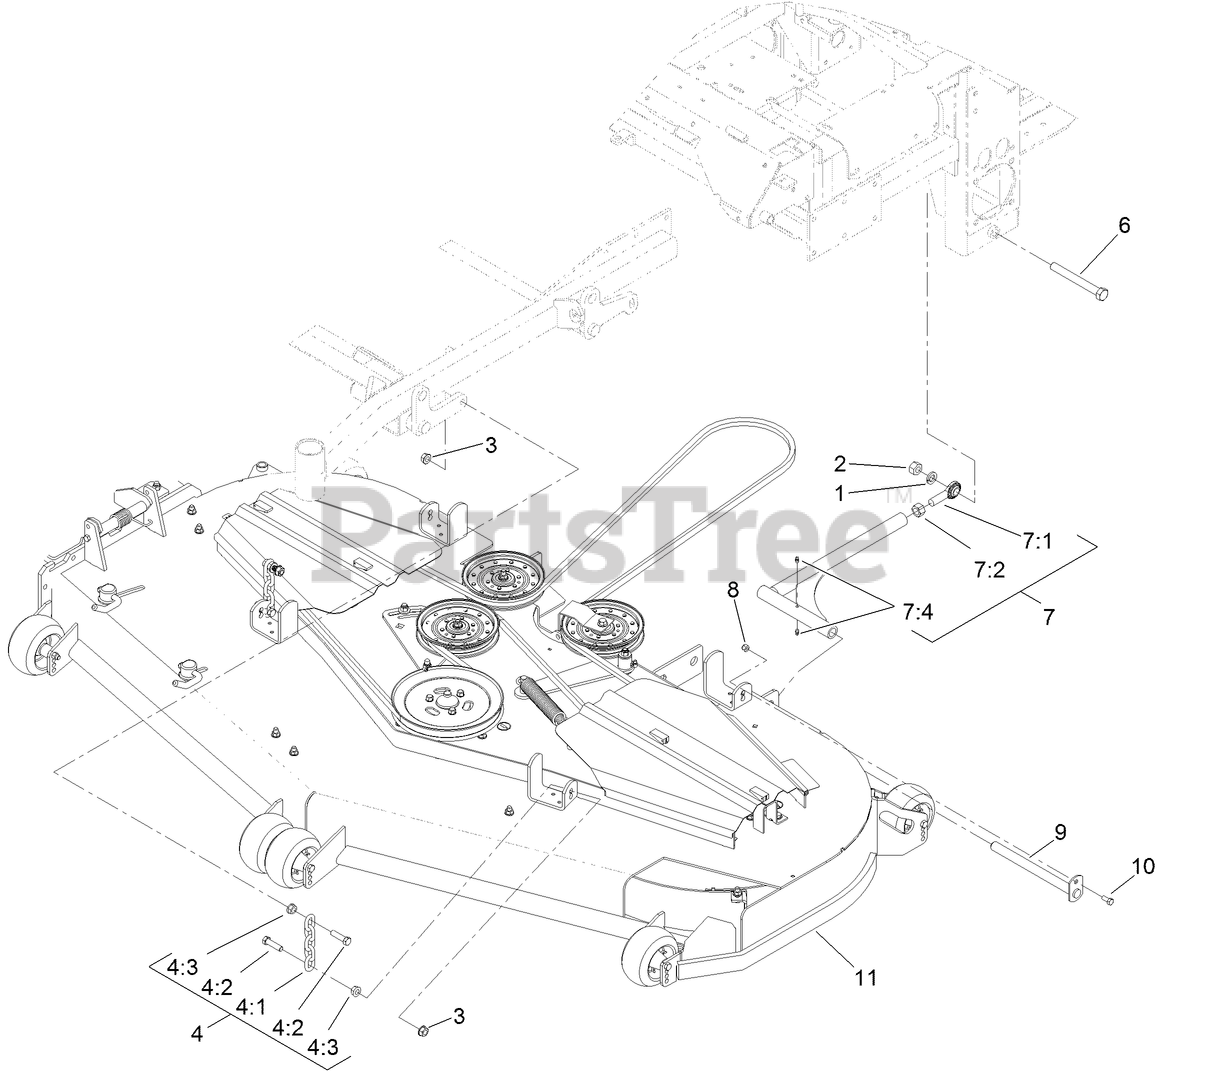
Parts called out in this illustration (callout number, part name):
1	WASHER-LOCK
2	NUT-HEX
3	NUT-HF
4	DECK CHAIN ASM
4:1	CHAIN-LIFT, DECK
4:2	SCREW-HH
4:3	NUT-HF
6	SCREW-HH
7	STRUT ASM
7:1	BALLJOINT-SPHERICAL
7:2	NUT-HEX
7:4	FITTING-GREASE
8	NUT-LOCK, NI
9	PIN-STRUT
10	SCREW-HH
11	DECK ASM
